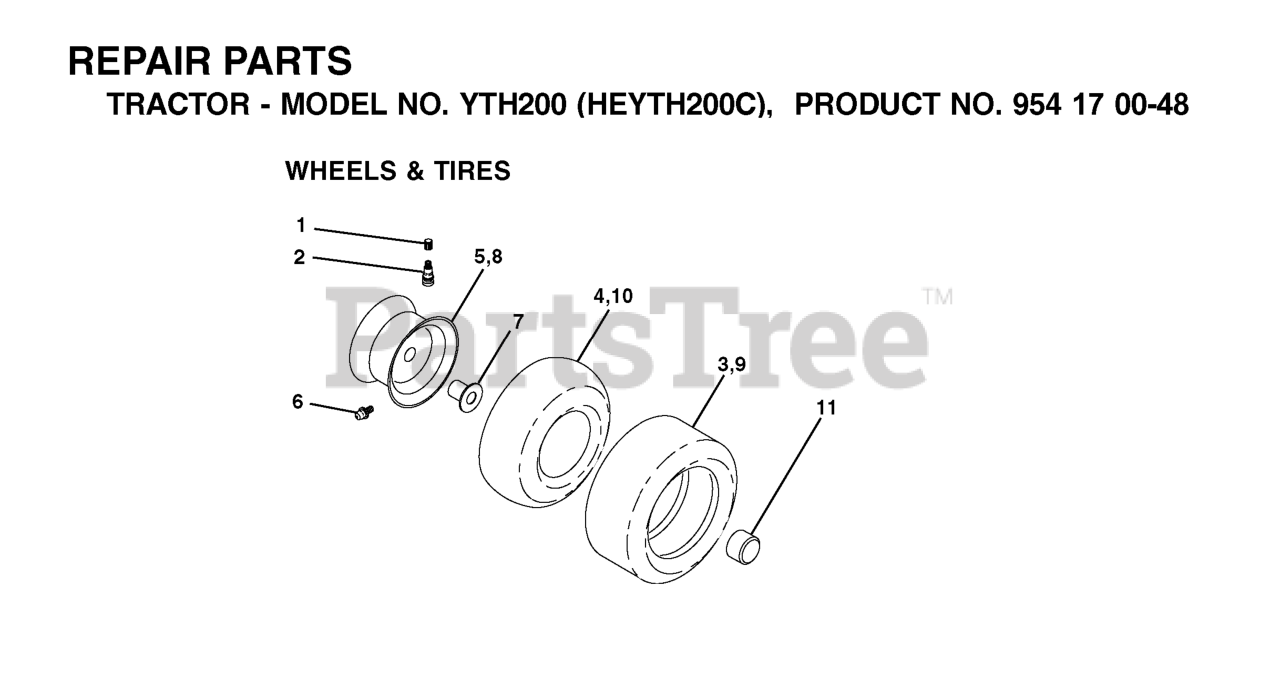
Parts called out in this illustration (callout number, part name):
2	VALVE STEM LT
3	TIRE HEAVY DUTY
4	TUBE.5.3/4.5/6
5	RIM ASM 6" FRONT SILVER
6	FITTING LT
7	BEARING T
8	RIM ASM 8" REAR SILVER
9	TIRE.TS.20X10-8
10	TUBE
11	CAP, AXLE BLK
